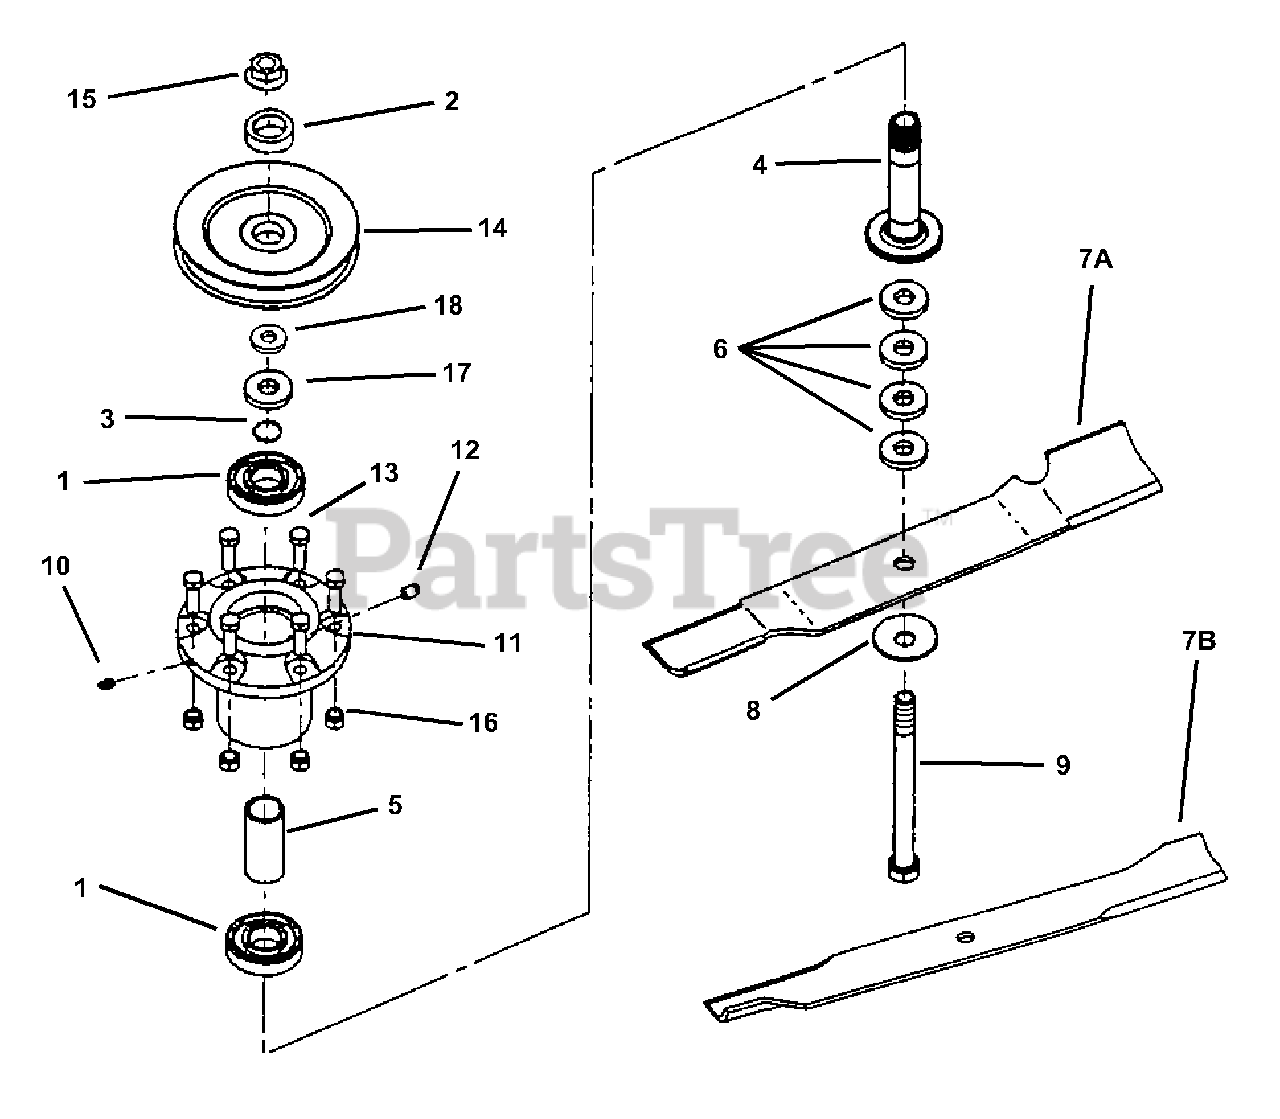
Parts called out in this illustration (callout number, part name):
1	BEARING, Sealed
2	WASHER, Spindle
3	SNAP-RING, Spindle Shaft
4	SHAFT, Spindle
5	SPACER, Bearing
6	SPACER, Blade
7A	BLADE, 18" (ZM5200M Mower)
7B	BLADE, Low Lift 18" (ZM5201M, ZM5202M Mower)
8	WASHER, Beveled
9	BOLT, 5/8-11 x 7-1/2" Hex Head Cap, Grade 5
10	LUBE FITTING, 1/4-28 Thread Forming
11	HOUSING, Cutter
12	VENT, Spindle
13	BOLT, 3/8-16 x 1-1/4" Rib Necked
14	PULLEY, 5-3/4" O.D.
15	NUT, 5/8-11 Hex Flange Grade 5
16	NUT, 3/8-16 HEX NYLON LOCK
17	SEAL, Nylos
18	WASHER
